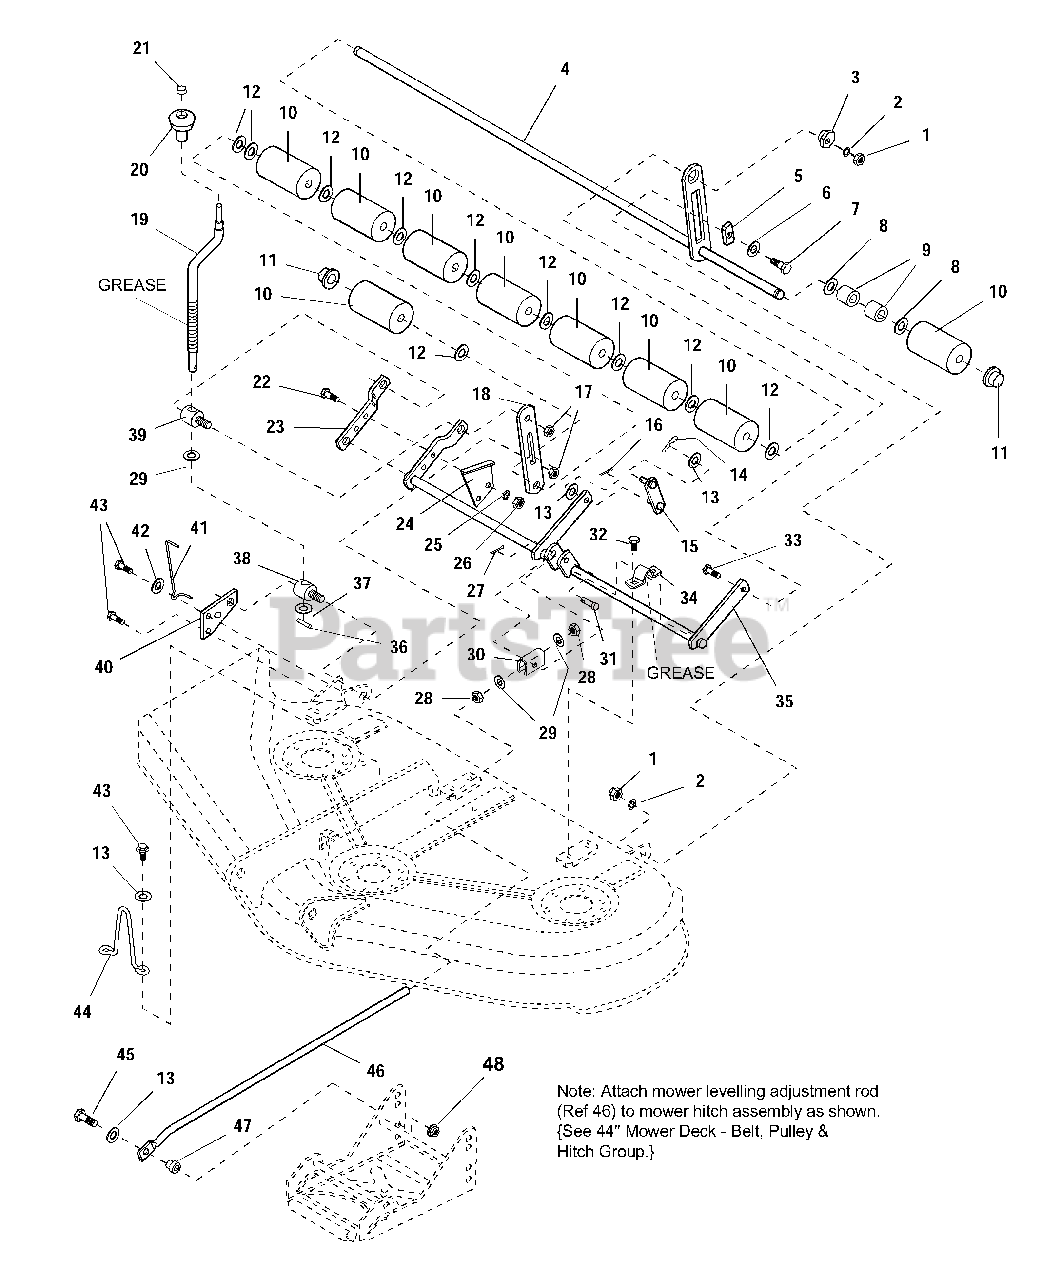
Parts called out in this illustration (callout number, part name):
1	NUT, Hex, 3/8-16
2	LOCKWASHER, 3/8
3	NUT, Hex Adjusting, .99 DIA .687
4	SHAFT ASSEMBLY, Roller, 44" (Includes Ref. Nos. 8, 9 & 11)
6	WASHER, Plain, 1/2
7	BOLT, Shoulder, 3/8-16 X 1.34
8	WASHER, 5/8
9	SPACER, .66 ID
11	NUT, Push
12	WASHER, 5/8
13	WASHER, Plain, 13/32
14	CLIP, Pin, Safety
15	LINK ASSEMBLY, Lift
17	NUT, Hex Flange Lock, 1/2-13
18	BAR, Roller
19	CRANK, Cutting Height
20	KNOB, Height Crank
21	PAL NUT
22	CAPSCREW, Hex Head, 5/16-18 x 1-1/4
23	ARM, Rear, Mower, RH
24	BRACKET, Cutting Height
26	NUT, Hex, 5/16-18
27	CLIP, Hair Pin
28	NUT, Hex Jam, 1/2-13
29	WASHER, 5/8
31	PIN, Clevis
32	CAPSCREW, Taptite, 5/16-18 x 3/4
33	CARRIAGE BOLT, 3/8-16 x 1-1/2
34	STRAP, Mower Arm ASSEMBLY
35	ARM ASSEMBLY, Mower
36	PIN, Roll, 1" Long
37	WASHER, Detent
39	TRUNNION, Threaded
40	PLATE, Mower Support
41	INDICATOR, Cutting Height
42	WASHER, Flat, 5/16
43	CAPSCREW, Taptite, 5/16-18 x 1-1/4
44	UP-STOP, Mower
45	CAPSCREW, Hex Head, 3/8-16 x 1-3/4
46	ROD, Adjustment
48	NUT, Hex Flange, 3/8-16
